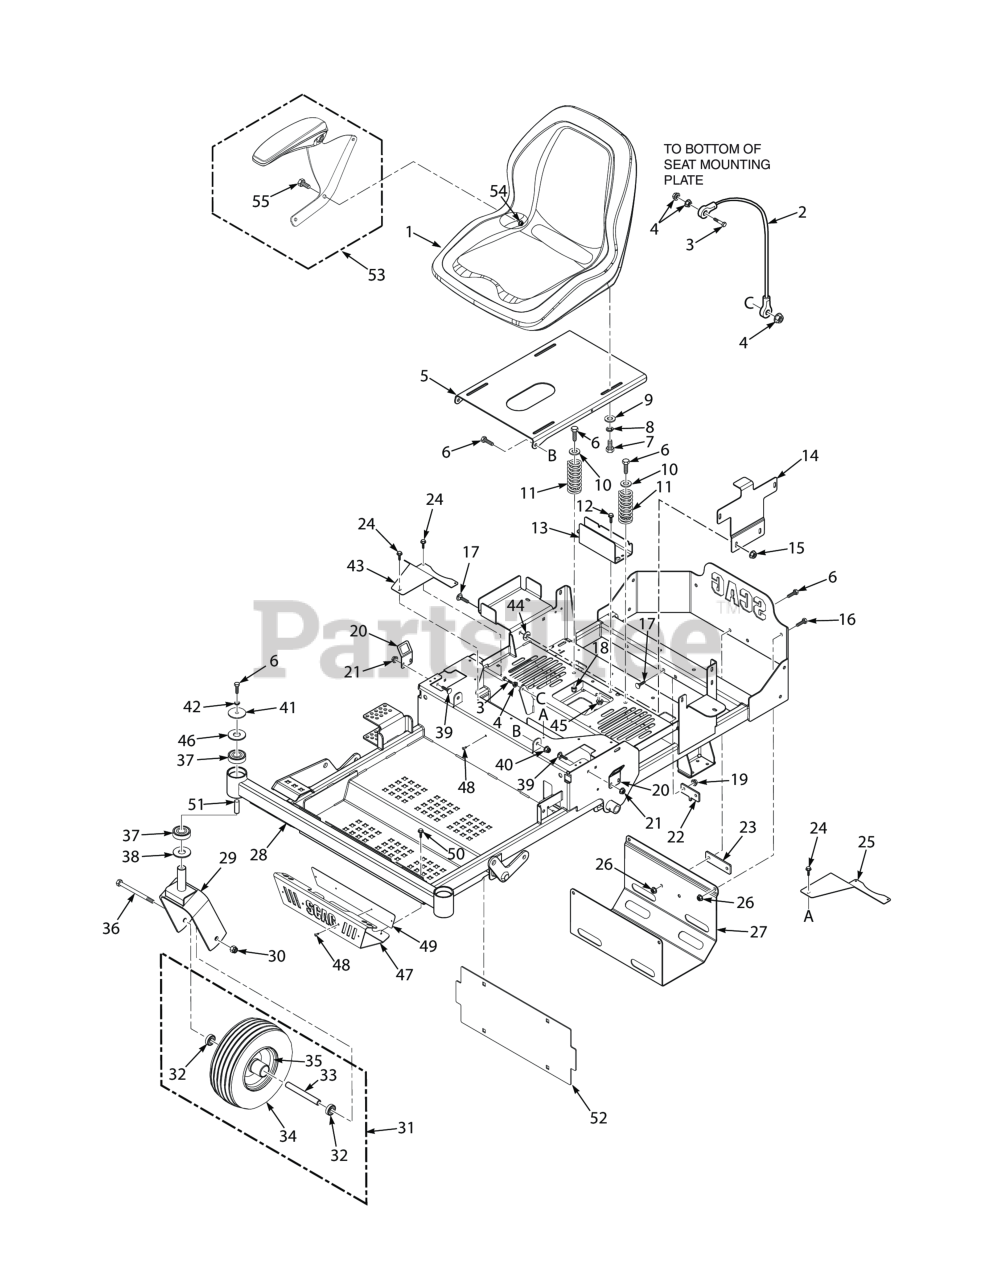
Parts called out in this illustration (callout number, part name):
1	Seat, SZL
2	Cable, Seat Stop
3	SERR. FLG. HEX HEAD CAPSCREW, 5/16-18 X 3/4
4	NUT, 1/4-20 SERRATED FLANGE HEX HEAD
5	Seat Plate w/Decal
6	Bolt, Hex Head, 3/8-16 x 1 Gr. 5
7	Bolt, Heax Head 5/16-18 x 1" (48V / 52V)
8	Lockwasher, 5/16 (.317 x .586 x .078) Helical Spring
9	Flatwasher, 5/16-.375 x .875 x .083 (35BV & 37BV-EFI)
10	Flatwasher, 3/8" Special (.391 x .938 x .105)
11	Spring, Seat
12	Capscrew, 5/16-18 x .75 Serrated Flange Hex Head
13	Channel, Hose
15	Nut, Flange Head Elastic Stop 5/16-18
16	Bolt, Hex Head, 3/8-16 x 3/4"
17	Bolt, 5/16-18 x .75 RHSN Carriage
18	HEX NUT, ELASTIC STOP LOCK, 3/8-16
19	Nut, Flange Head Elastic Stop 5/16-18
20	Bracket, Switch
21	Nut, Flanged Elastic Stop 1/4-20
22	Plate, Anti-Rotation
23	Plate, Spacer
24	Screw, #10-32 x .563 Shakeproof
25	Guard, Belt - LH
26	NUT, 3/8-16 SERRATED FLANGE HEX HEAD
27	Skid Plate, SZL
28	Mainframe w/Decals - SZL-61
29	Caster Assembly
29	Yoke, Caster Wheel
30	HEX LOCKNUT, ELASTIC STOP, 1/2-13
31	CASTER WHEEL ASSY, 11.00 X 6.00-5
32	Bearing
33	SPACER, WHEEL BEARING
34	TIRE, 11 X 6.00-5
35	RIM ASSY, 5 X 3 W/5.625 LG HUB
36	Bolt, Hex Head 1/2-13 x 7-1/2" (48"/52")
37	Bearing
38	Spacer, Yoke
39	Serr. Fl. Hex Head CPSCR, 1/4-20 x 3/4"
40	Nut, Flange Elastic Stop Nut, 3/8-16
41	Flatwasher, 3/8-.406 x 2.25" x .1875
42	Lockwasher, 3/8" Spring, Kawasaki FX / FS
43	GUARD, BELTS - RH
44	Nut, Push-On 5/16-18
45	Nut, Serrated Flange 5/16-18 (Right Front Engine Mounting, Briggs and Kohler Only)
46	Flatwasher, 7/16" (.500 x 1.25 x .083")
47	Bumper. Front
48	Rivot, 3/16 x .402 POP
49	Plate, Decal
50	Screw, 1/4-20 x .375"
51	Spacer, Caster Bearing
52	Plate, Backing
53	SZL Armrest Kit
54	SPEED U-NUT,1/4-14
55	SCR,HHSCR, 1/4-14 X1 TYPA THRD FRMNG
